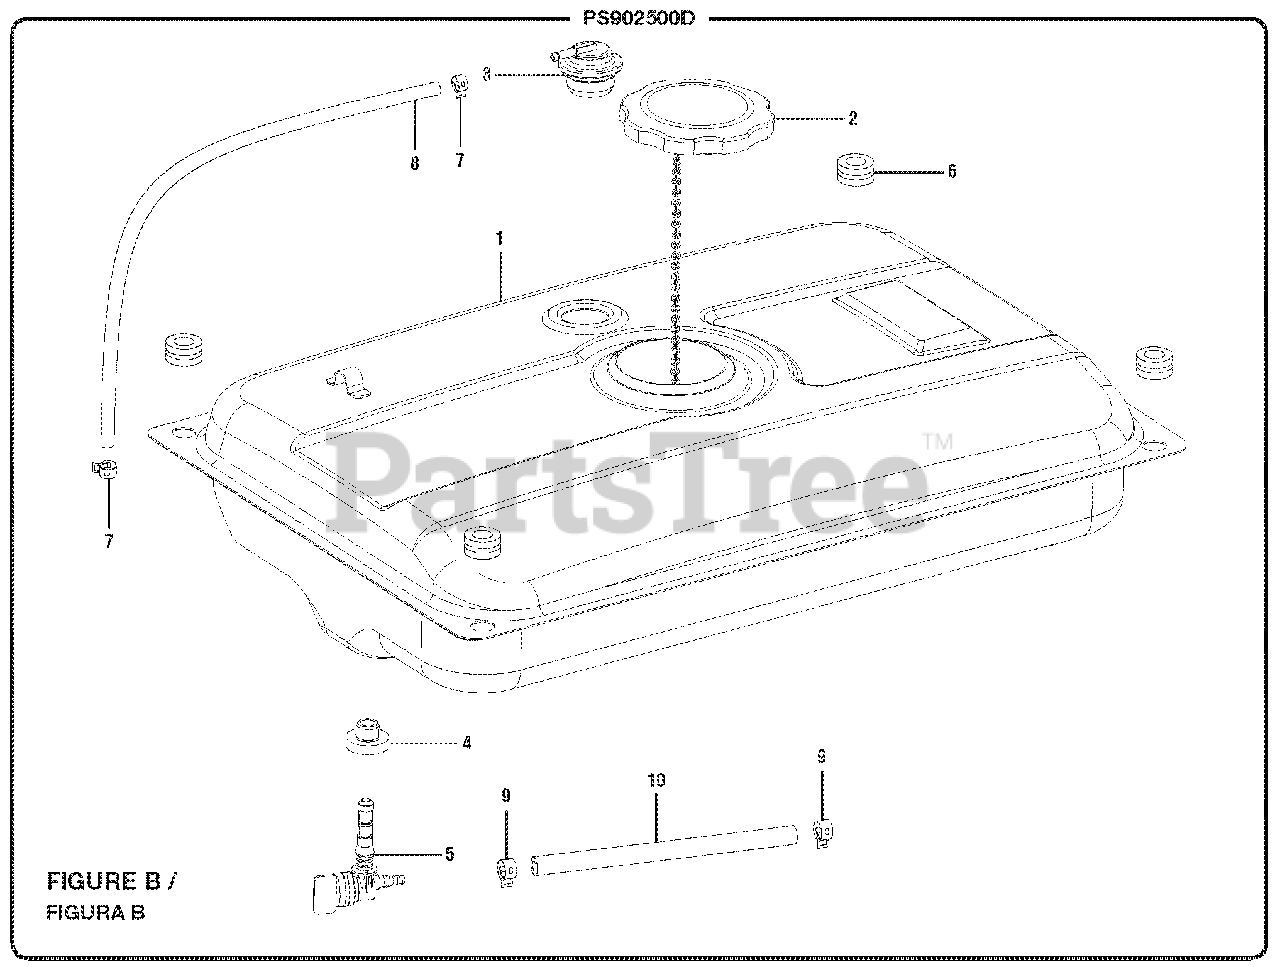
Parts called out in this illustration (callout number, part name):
3	Fuel Tank Vapor Vent
4	Fuel Tank Bushing
5	Fuel Valve w/Filter
6	Fuel Tank Isolator.
7	Fuel Hose Clamp (D7)
8	Fuel Line (760 mm)
9	Fuel Hose Clamp (D11)
10	Fuel Hose
